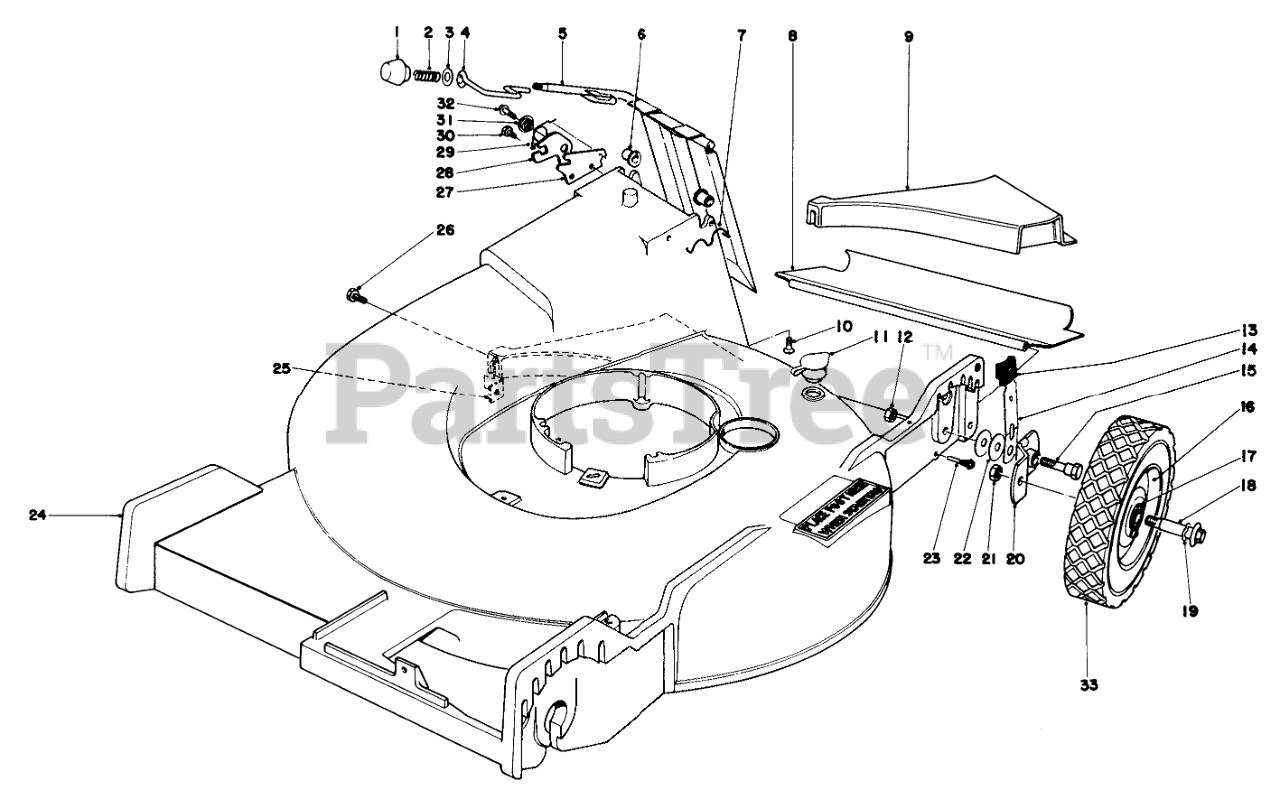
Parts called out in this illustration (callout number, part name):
2	COMPRESSION SPRING
3	WASHER
4	DOOR LATCH
5	Door Handle
6	BUSHING-NYLON
7	Door Retainer
8	REAR SAFETY SHIELD
9	REAR INSERT
10	SCREW-HH
11	WASHOUT PLUG
12	Nut
13	KNOB-ARM
14	SPRING ARM ASM
15	PIVOT SCREW
16	Wheel & Tire Assembly (Incl. Ref. #17 & 33)
17	BEARING-BALL
19	SPRING WASHER
20	PIVOT ARM ASM A
21	Nut
22	WASHER-PIVOT
23	SAFTEY SHIELD SCREW
24	Housing
25	SPECIAL NUT
26	SCREW THD 1/4 20 5/8
27	DOOR LATCH PLATE
28	Latch Safety
29	TORSION SPRING
30	SCREW-HWH
31	Latch Spacer
32	Screw
